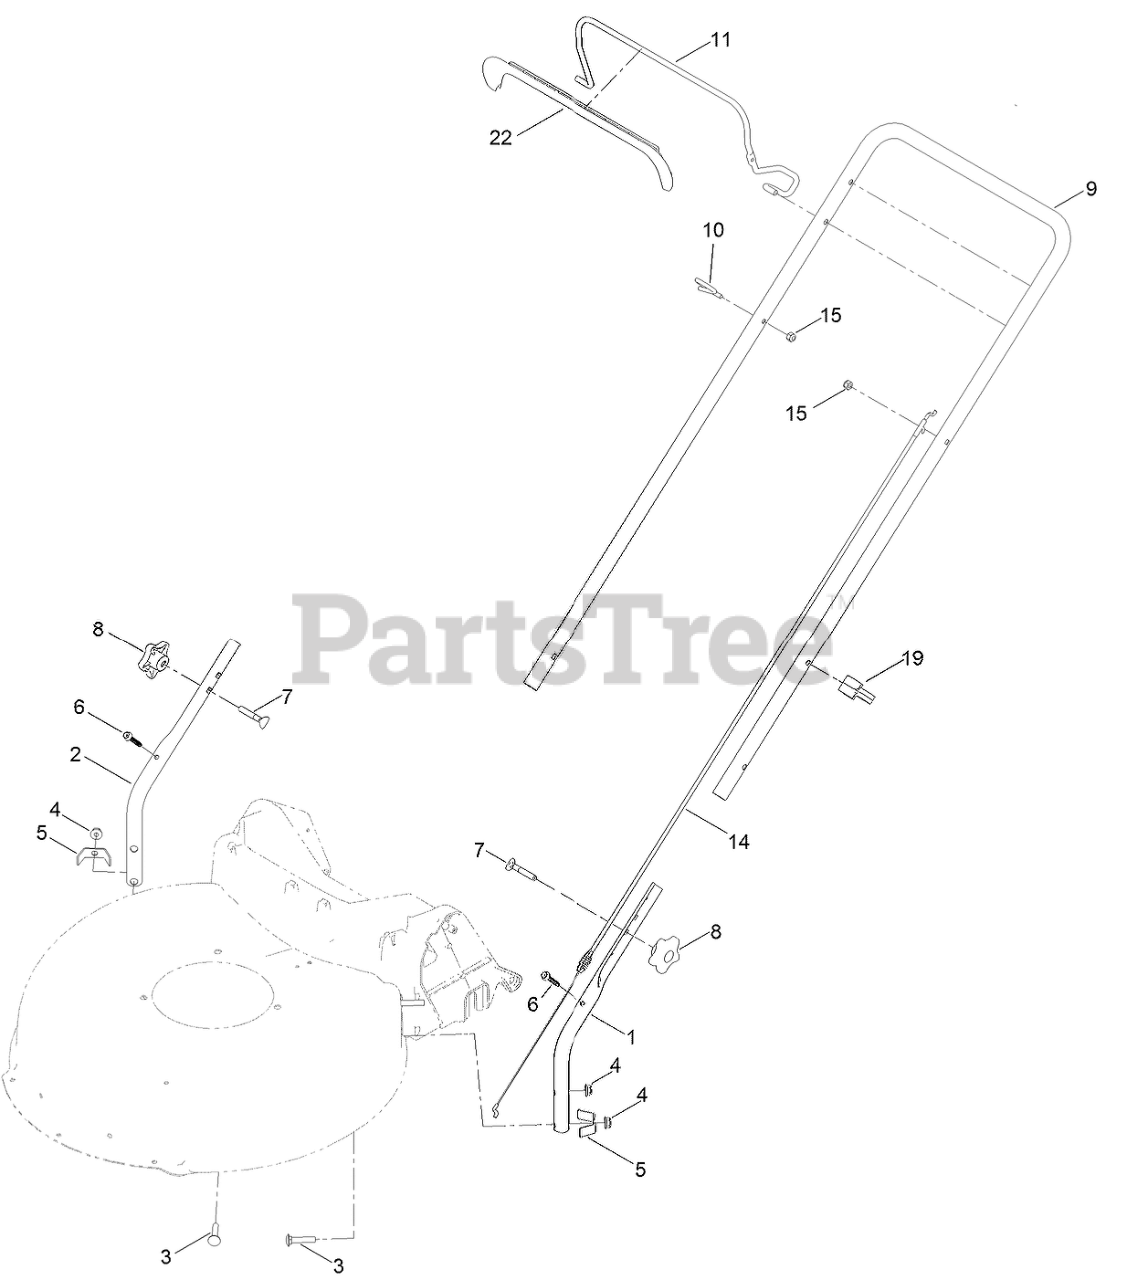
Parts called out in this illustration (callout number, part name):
1	HANDLE-LOWER, LH
2	HANDLE-LOWER, RH
3	BOLT-CARR
4	NUT-FLANGE, NI
5	BRACKET-CHUTE
6	SCREW-FLANGE, SERRATED
7	SCREW-HANDLE
8	KNOB-HANDLE
9	HANDLE-UPPER
10	GUIDE-ROPE
11	BAIL-BRAKE
14	CABLE-BRAKE, ENGINE
15	NUT-LOCK, NI
19	GUIDE-CABLE
22	COVER-BAIL
